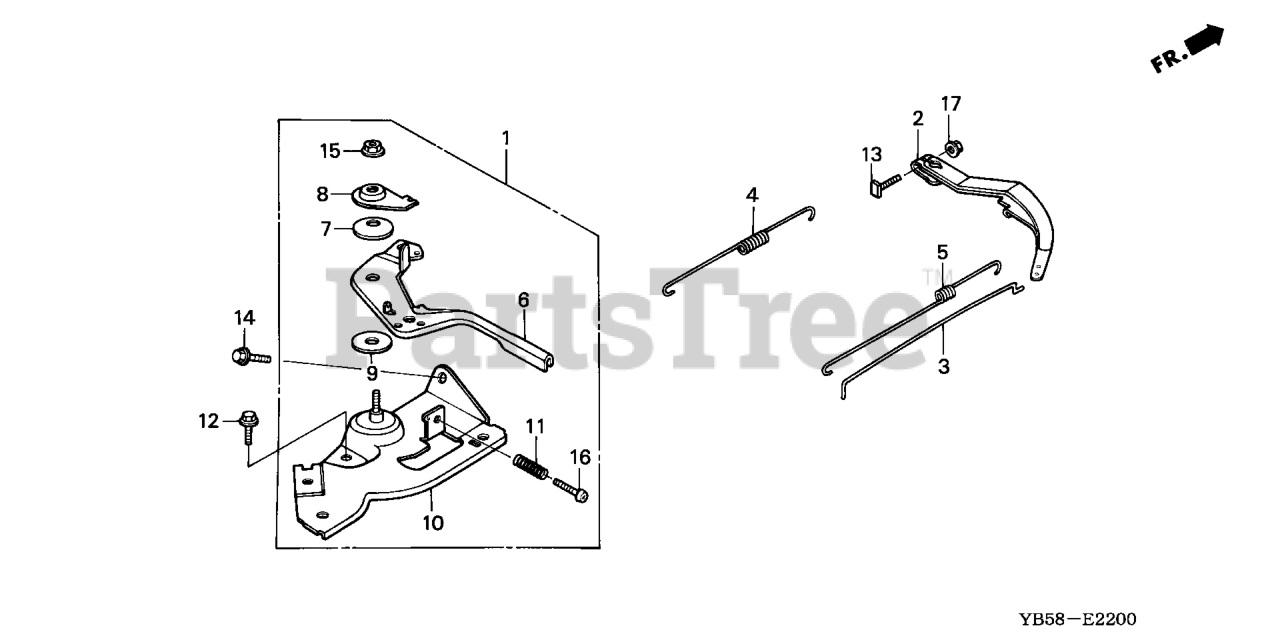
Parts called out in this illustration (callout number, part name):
1	CONTROL ASSY.
2	ARM, GOVERNOR
3	ROD, GOVERNOR
4	SPRING, GOVERNOR
5	SPRING, THROTTLE RETURN
6	LEVER, CONTROL
7	SPRING, LEVER
8	WASHER, CONTROL LEVER
9	SPACER, CONTROL LEVER
10	BASE, CONTROL
11	SPRING, CONTROL ADJUSTING Use from Engine SN 2327377.
12	BOLT, FLANGE (6X12) (CT200)
13	BOLT, GOVERNOR ARM
14	BOLT, FLANGE (6X20) (CT200)
15	NUT, SELF-LOCK (6MM)
16	SCREW, PAN (5X25)
16	SCREW, PAN (5X28)
17	NUT, FLANGE (6MM)
